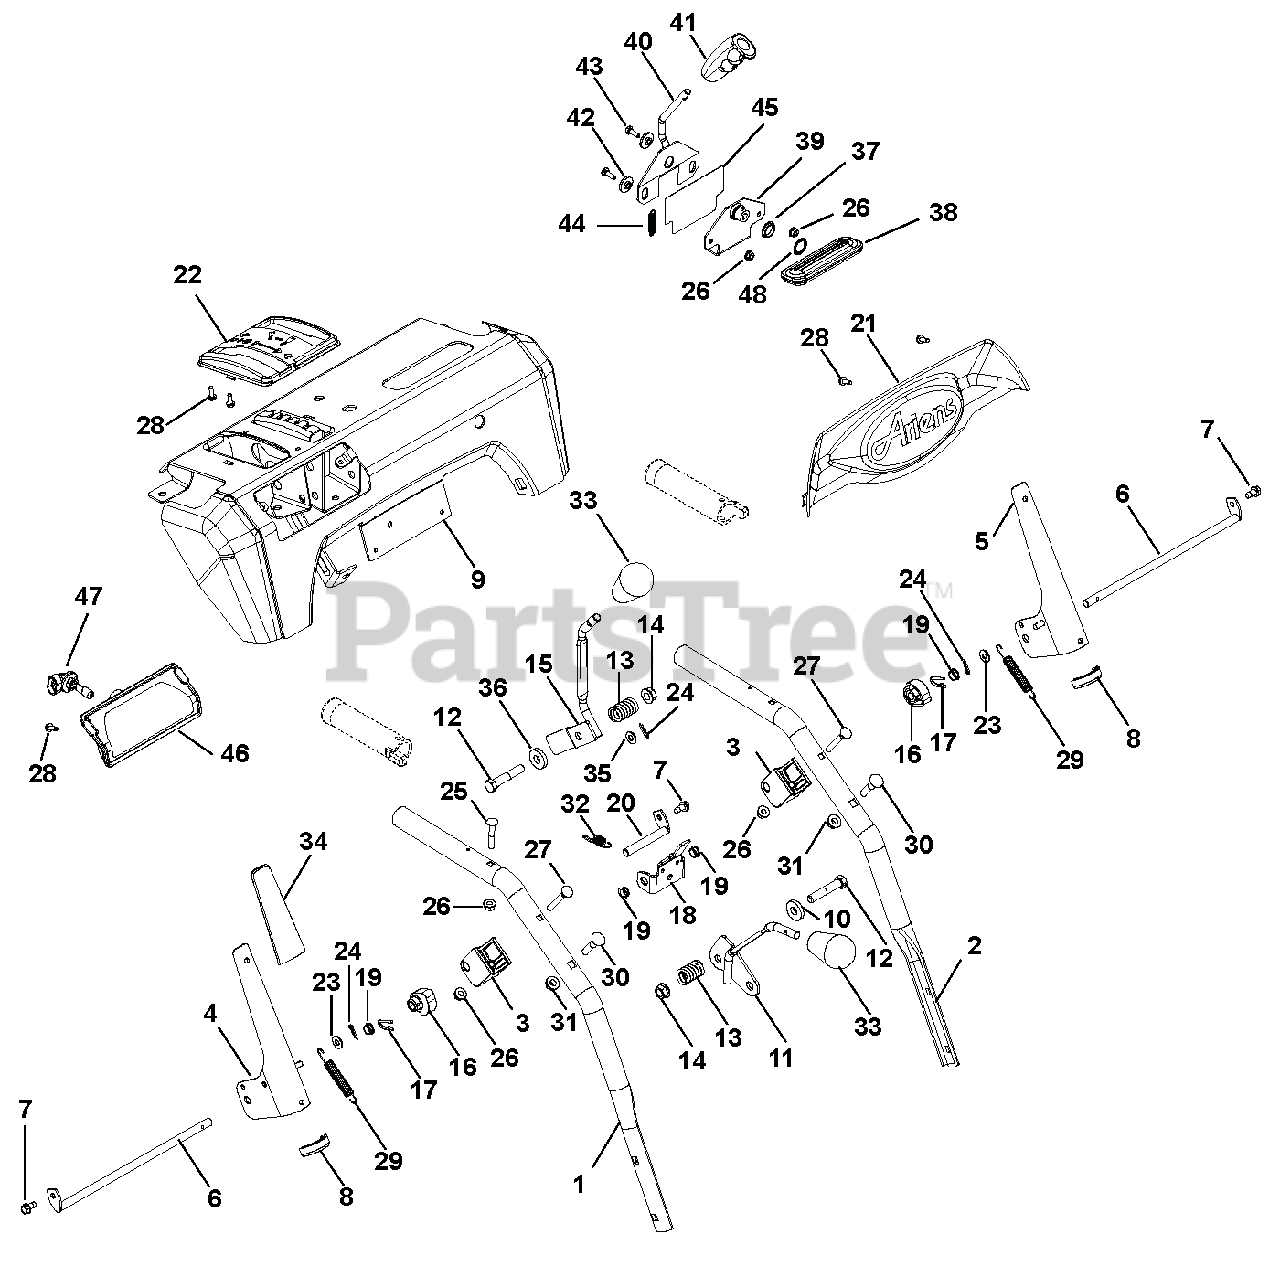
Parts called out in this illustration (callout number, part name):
1	HANDLEBAR, UPPER RH W/HW
2	HANDLEBAR, UPPER LH W/HW
3	BLOCK, CLUTCH PADDLE
4	LEVER, CLUTCH-RH
5	LEVER, CLUTCH-LH
6	ROD, PADDLE MOUNT - PRO
7	SCR-TAP .25-20X.50 HWH TR YWZ
8	EDGING, CLUTCH PADDLE - 2.00"
9	CONTROL PANEL W/DECAL,QT,HW,AD
9	CONTROL PANEL W/DECAL QT,HW,TK
9	CONTROL PANEL W/DECAL 12V,HW
10	WSHR-FL-STL .406X1.00X.188 YWZ
11	WELDMENT, CONTROL LEVER(SHIFT)
12	@BLT-HEX .38-16X2.00 GR5 YWZC
13	SG-COMP .125X.781X1.250
14	@NUT-LK-TOP-FLG .38-16 YWZC
15	WELDMENT, CONTROL LEVER (DEFL)
16	CAM, INTERLOCK
17	PIN, SPRING CLIP
18	BRACKET, INTERLOCK ARM
19	BUSHING, POLYLINER-.38 SNAPIN
20	ROD, PIVOT - INTERLOCK
21	DASH BEZEL, ARIENS LOGO - PRO
22	SHIFT BEZEL W/ NEUTRAL
23	@WSHR-FL-STL.281X.62X.065 YWZC
24	PIN-HAIR INT .06X.18X.77
25	BLT-RDHDXLSQNK.25-20X1.25 G5ZC
26	@NUT-LK-CTR-FLG .25-20 YWZC
27	BLT-RDHDXLSQNK .25-20X2.0 G5YZ
28	SCR-TAP #10X.50 BOSS INDHXHD
29	SPRING, EXTENSION
30	@BLT-RDHDSQNK .31-18X1.50 G5YZ
31	@NUT-LK-TOP-FLG .31-18 YWZC
32	SPRING-EXT .047X.438X1.45
33	KNOB,SOFT TEARDROP,PUSH-ON GRY
34	CLUTCH PADDLE SLEEVE - GRAY
35	BSHG-SLV .265X.500X.219
36	WSHR-FL-STL .380X1.50X.062 YWZ
37	BUSHING, POLYLINER-.75 SNAPIN
38	GROMMET-BOOT, QUICKTURN
39	MOUNT, CHUTE CONTROL
40	LEVER, CHUTE CONTROL
41	CONTROL HANDLE, QUICK TURN
42	BSHG-FLG .265X.448X.243X1.00
43	@BLT-HEX .25-20X.75 GR5 YWZC
44	SG-TENS .048X.44X1.75 WLD 9
45	TAPE, DIE CUT - QUICK TURN
46	HEADLIGHT ASSY, HALOGEN 20W
47	BULB, LIGHT-HALOGEN 20W
48	NUT, PUSH -.75" SHAFT
